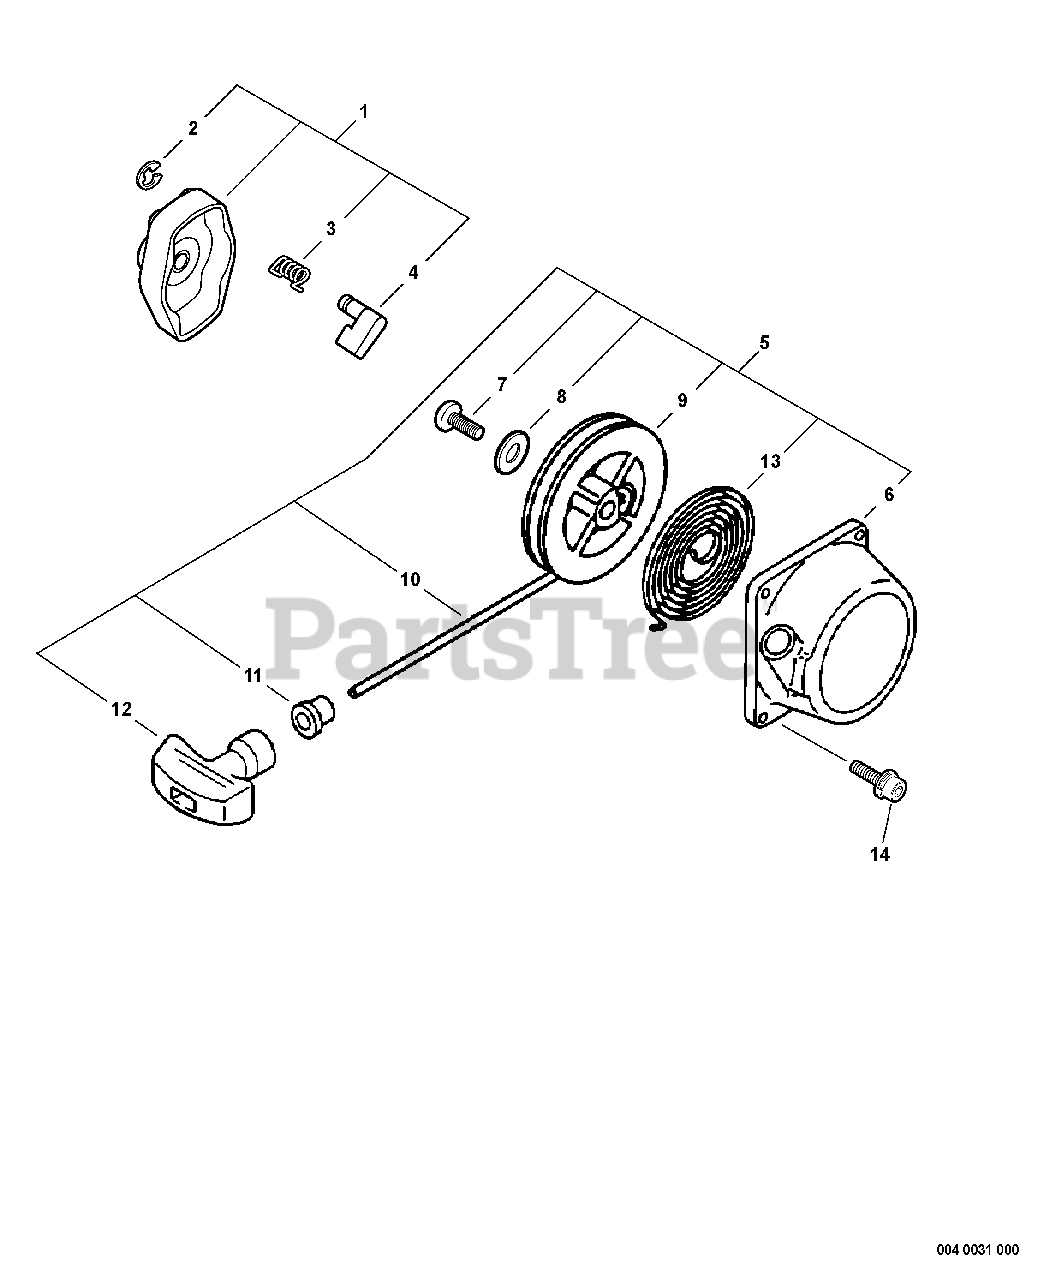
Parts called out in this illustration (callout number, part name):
1	STARTER PAWL ASSY
2	RING, RETAINING - 4
3	SPRING, RETURN
4	PAWL, STARTER
5	STARTER ASSY
6	CASE, STARTER
8	WASHER
9	REEL, ROPE
10	ROPE, STARTER - 4X1110
11	GUIDE, ROPE
12	GRIP, STARTER
13	SPRING, REWIND
14	SCREW - 4X18
